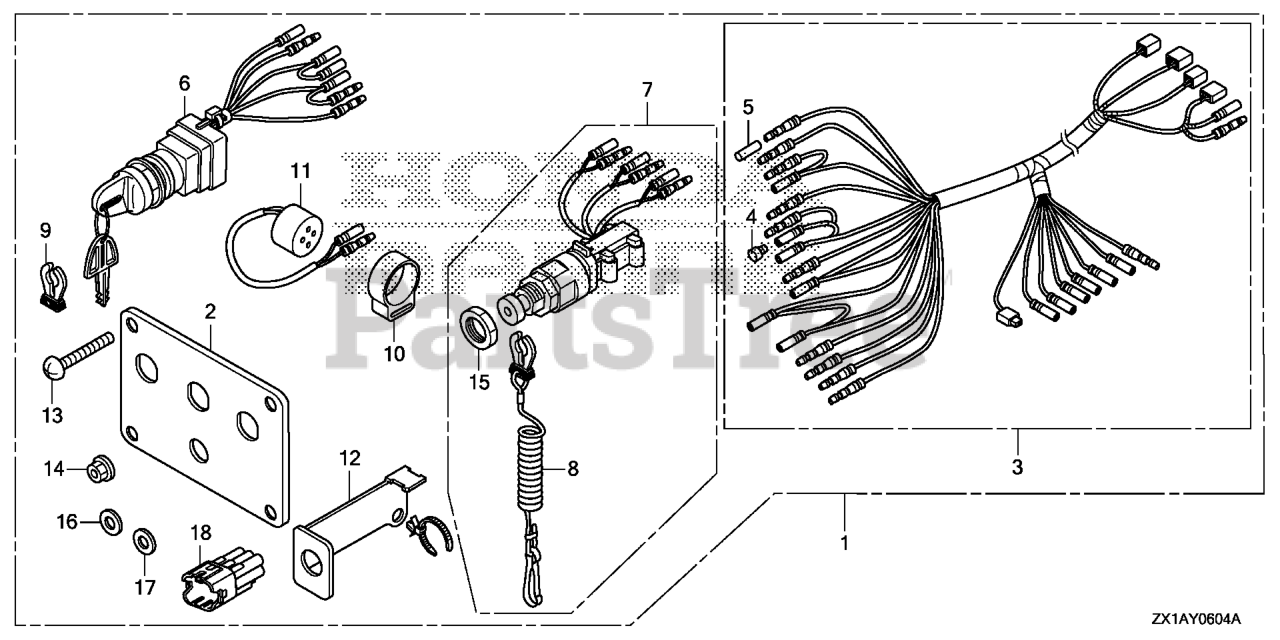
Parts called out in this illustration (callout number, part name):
1	PANEL KIT, SWITCH (TRIPLE)
1	PANEL KIT, SW
2	PANEL, CONTROL (TRIPLE)
3	HARNESS ASSY., SWITCH PANEL
4	PLUG, CONNECTOR (INNER) (TROLLING CONTROL)
5	PLUG, CONNECTOR (OUTER) (ENGINE NO.)
6	SWITCH ASSY., COMBINATION
7	SWITCH ASSY., EMERGENCY STOP (TRIPLE)
8	WIRE, EMERGENCY
9	CLIP, EMERGENCY LOCK
10	SUSPENSION, AUDIBLE PILOT
11	BUZZER, WARNING
12	BRACKET
13	SCREW, PAN (5X40) DUAL QTY = (8) (SINGLE)
14	NUT, FLANGE (5MM)
15	NUT
16	WASHER, PLAIN (5MM)
17	WASHER, SPRING (5MM)
17	WASHER, SPG (5MM)
18	DUMMY, WATERPROOF CONNECTOR (GREEN)
